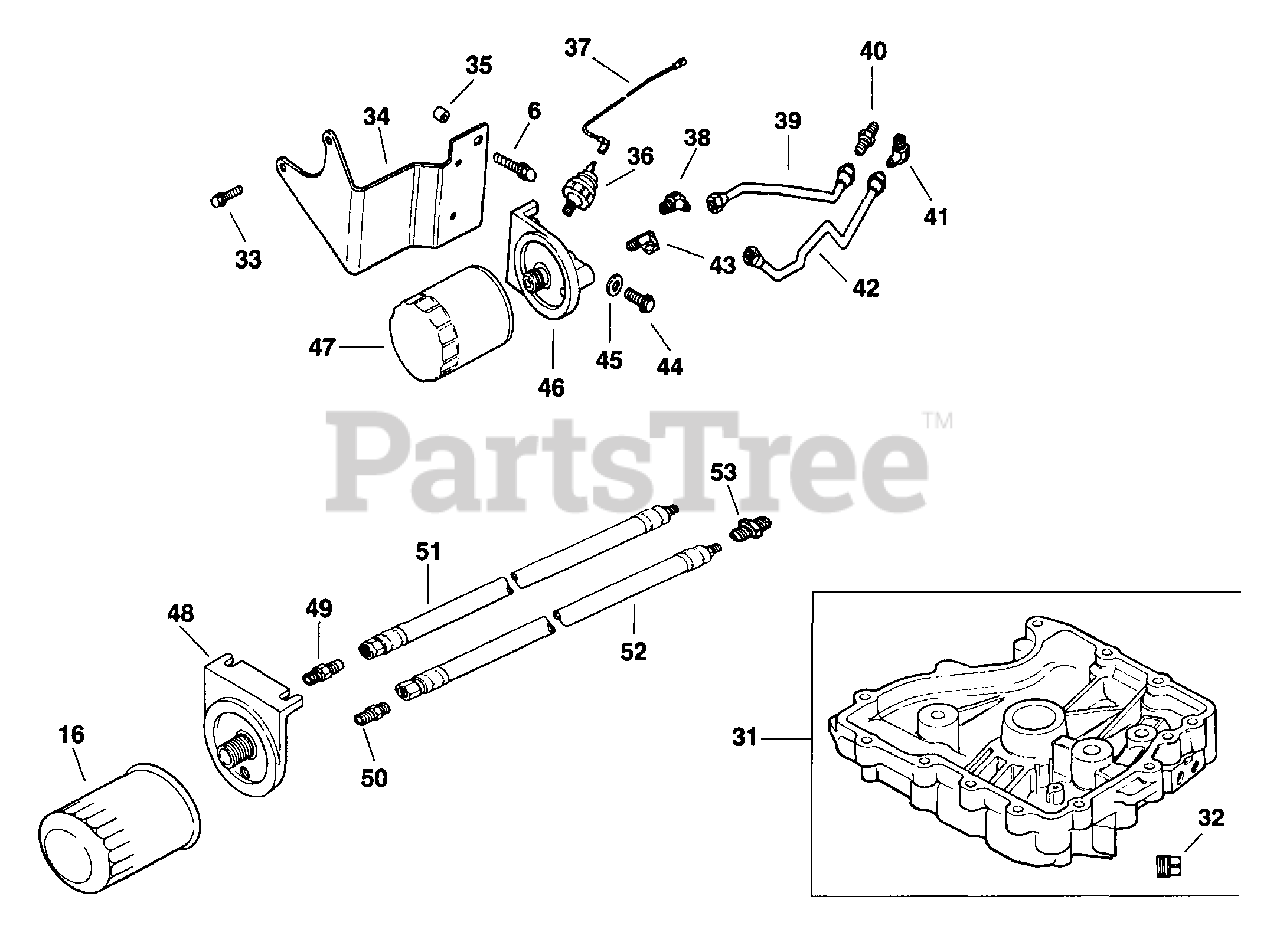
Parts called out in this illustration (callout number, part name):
6	Screw, hex. flange M5x0.8x20
16	OIL FILTER
32	PLUG, CTSK PIPE 1/8" USE 25 139 60-S
